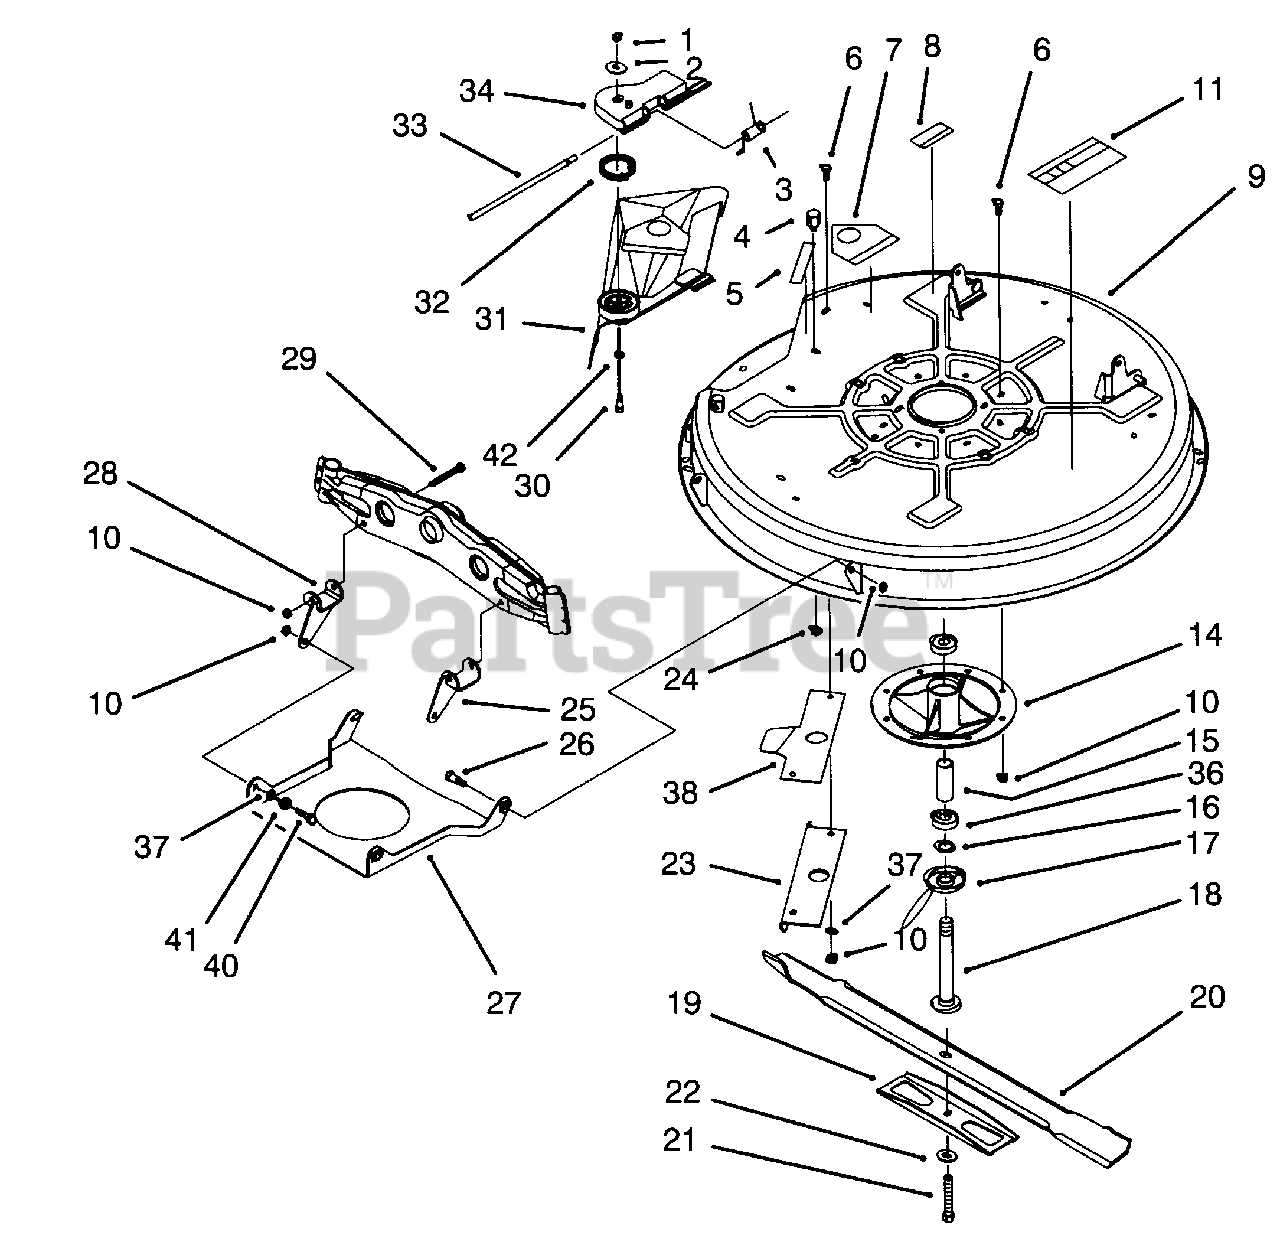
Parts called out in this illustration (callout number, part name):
1	Nut-Lock
2	Washer-Fender
3	Spring-Torsion
4	Post-Rear Pivot
5	Decal-Deflector Danger
6	Screw-Hex Hd. Cap
7	Decal-Danger
8	Decal-Caution
9	Cutter Deck-32"
10	Nut-Lock
11	Decal-Danger
14	Housing-Spindle
15	Spacer-Bearing
16	Spacer-Hardened
17	Shield-Bearing
18	Shaft-Spindle
19	Stiffener-Blade
20	Blade-32"
21	Bolt-Blade
23	Baffle-Deck
24	Nut-Lock
25	Bracket-L.H.
26	Bolt-Shoulder
27	Pan-Front Suspension
28	Bracket-R.H.
29	Screw-Hex Hd. Cap
30	Bolt-Shoulder
31	Deflector-Double Pivot
32	Spring-Torsion
33	Rod-Deflector Hinge
34	Hinge-Deflector Danger
36	Bearing-Spindle
37	Washer-Flat
38	Ramp-Deflector
40	Screw-Hex Hd. Cap
42	Spacer-Deflector
